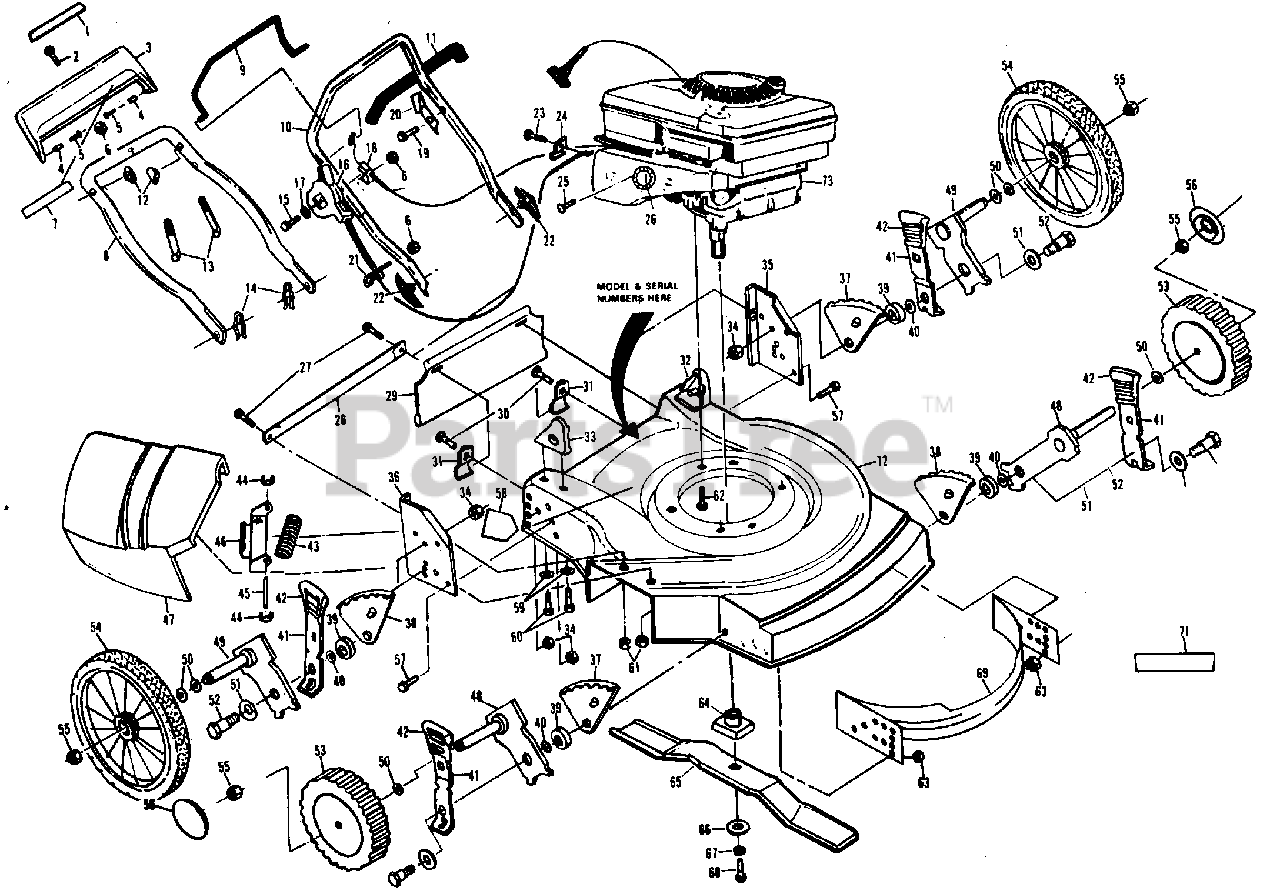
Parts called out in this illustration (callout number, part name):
1	Trim Plate Decal 5.0 HP
2	Hex Washer Head Machine Screw (AYP part number)
3	Trim Plate
4	Nylon Bushing (AYP part number)
5	Tapping Screw (AYP part number)
6	Locknut (AYP part number)
7	Trim Plate Decal (AYP part number)
8	Lower Handle (AYP part number)
9	Control Bar
10	Upper Handle
11	Handle Grip (AYP part number)
12	Handle Bolt
13	Wire Tie (AYP part number)
14	Hairpin Cotter (AYP part number)
15	Machine Screw (AYP part number)
16	Throttle Control
17	Flat Washer (AYP part number)
18	Engine Zone Control Cable (AYP part number)
19	Hex Washer Head Screw (AYP part number)
20	Up-Stop Bracket (AYP part number)
21	Rope Guide (AYP part number)
22	Screw (AYP part number)
23	Thread Rolling Screw (AYP part number)
27	Hex Tapping Screw (AYP part number)
28	Support Rod (AYP part number)
29	Rear Skirt (AYP part number)
30	Hex Washer Head Tapping Screw (AYP part number)
31	Rear Skirt Bracket (AYP part number)
32	Handle Bracket Assembly (Left)
33	Handle Bracket Assembly (Right)
34	Locknut (AYP part number)
35	Wheel Support Bracket (Left)
36	Wheel Support Bracket (Right)
37	Wheel Adjusting Bracket (L.R & R.F)
38	Wheel Adjusting Bracket (R.R. & L.F.)
39	Spacer (AYP part number)
40	Flat Washer (AYP part number)
41	Selector Spring (AYP part number)
42	Selector Knob (AYP part number)
43	Torsion Spring (AYP part number)
44	E-Ring (AYP part number)
45	Hinge Rod (AYP part number)
46	Housing Bracket Assembly (AYP part number)
47	Discharge Guard (AYP part number)
48	Axle Arm Assembly (Front) (AYP part number)
49	Axle Arm Assembly (Rear) (AYP part number)
50	Wave Washer (AYP part number)
51	Belleville Washer (AYP part number)
52	Shoulder Bolt (AYP part number)
53	Wheel & Tire Assembly
54	Wheel & Tire Assembly
55	Locknut (AYP part number)
57	Hex Head Bolt (AYP part number)
58	Danger Decal (AYP part number)
59	Flat Washer (AYP part number)
60	Thread Cutting Screw (AYP part number)
61	Locknut (AYP part number)
62	Hex Head Thread Rolling Screw (AYP part number)
63	Locknut (AYP part number)
64	Blade Adapter (AYP part number)
65	Blade 22"
66	Hardened Washer (AYP part number)
67	Helical Lockwasher (AYP part number)
68	Hex Head Screw
69	Front Baffle (AYP part number)
71	"Poulan" Decal (AYP part number)
72	Lawn Mower Housing
